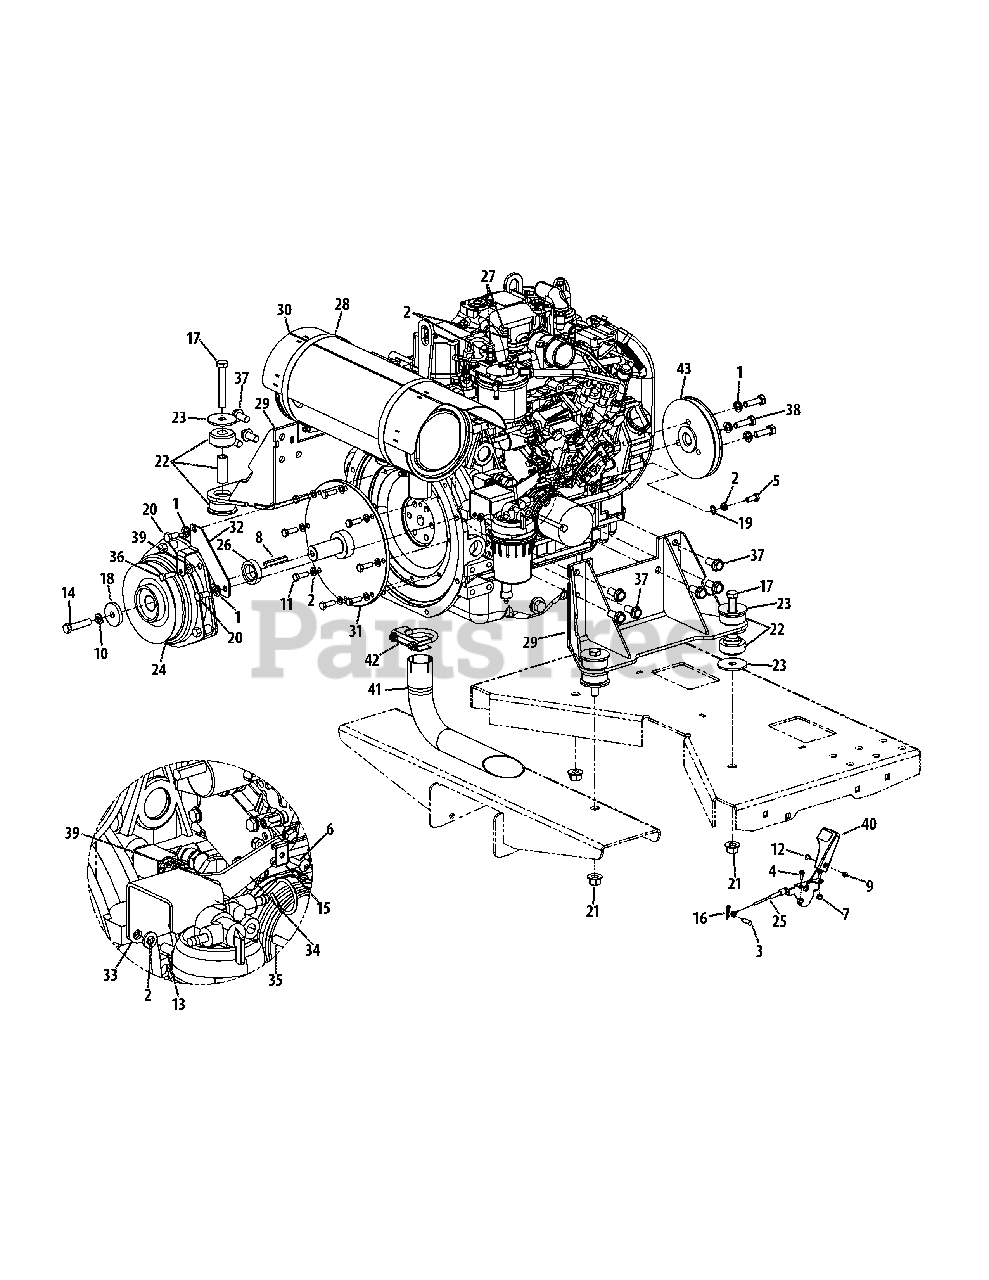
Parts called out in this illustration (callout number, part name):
1	Washer, 10 x 17.8 x 3.6
2	Lock Washer, .312 x .583 x .083
3	Clevis Pin, 1/4 x .750
4	Hex Flange Screw, #10-32 x .500
5	Hex Screw, M8-1.25 x 18
6	Machine Screw, #10-32 x .750
7	Nut, #10-32
8	Key, .250 x .250 x 2.00
9	Nut, #8-32
10	Lock Washer, .490 x .776 x .114
11	Hex Screw, M8-1.25 x 25
12	Machine Screw, #8-32 x .356
13	Hex Screw, M8-1.25 x 20
14	Hex Screw, 7/16-20 x 2.00
15	Cable Throttle Clamp
16	Hair Pin, 1/8 x 1.125 x .072
17	Hex Screw, 1/2-13 x 3.25
18	Washer, .438 x 1.745 x .250
19	External Tooth Washer
20	Hex Screw, M10-1.5 x 20
21	Flange Top Lock Nut, 1/2-13
22	Engine Isolater
23	Washer, .53 x 2.13 x .134
25	Throttle Control Cable
26	Spacer, 1.14 x 1.75 x .438
27	Hex Screw, M8-1.25 x 30
28	Hose Clamp
29	Engine Bracket
30	Muffler Heat Shield
31	Clutch Drive Shaft
32	Clutch Retainer Bracket
33	Diesel Fuel Seperator Mount Bracket
34	Throttle Mount Bracket
35	Hex Screw, 5/16-18 x 2.75
36	Hex Screw, 5/16-18 x 1.00
37	Hex Flange Screw, M12-1.75 x 25
38	Hex Screw, M10-1.5 x 35
39	Flange Lock Nut, 5/16-18
40	Throttle Control Knob
41	Elbow Exhaust Pipe
42	Muffler Clamp
43	Transmission Drive Pulley
